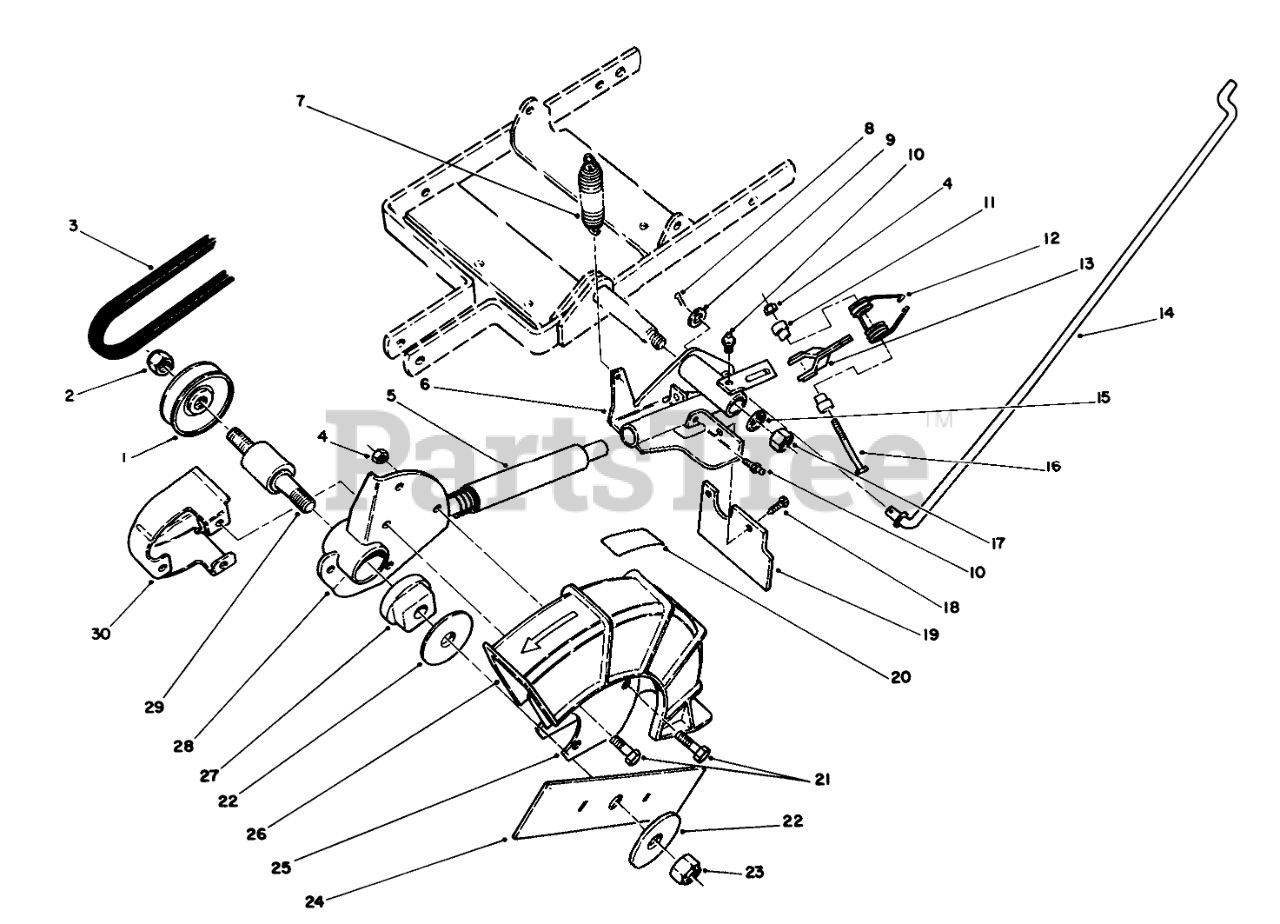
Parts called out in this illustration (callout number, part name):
1	PULLEY
2	NUT-LOCK, NI
3	V-BELT
4	NUT-LOCK, NI
5	SPRING & BELLOW ASM
6	PIVOT ARM WELDMENT B
7	EXT. SPRING
8	PIN-COTTER
9	WASHER-FLAT
10	FITTING-GREASE
11	SPACER-PIVOT LEVER
12	TORSION SPRING
13	LEVER WA
14	LOWER CONTROL ROD
15	WASHER-PLAIN
16	SCREW-HH
17	NUT-LOCK, NI
18	PANEL FASTENER
19	RUBBER GUARD
20	DECAL-BLADE
21	SCREW-HWHTF
22	WASHER-LARGE
23	NUT-HEX
24	10" EDGER BLADE B
25	GUARD PLATE
26	Guard-Blade (Incl. Ref. #20)
27	BRG SHIELD
28	HUB ASM
29	SPINDLE ASM
30	PULLEY GUARD WA
